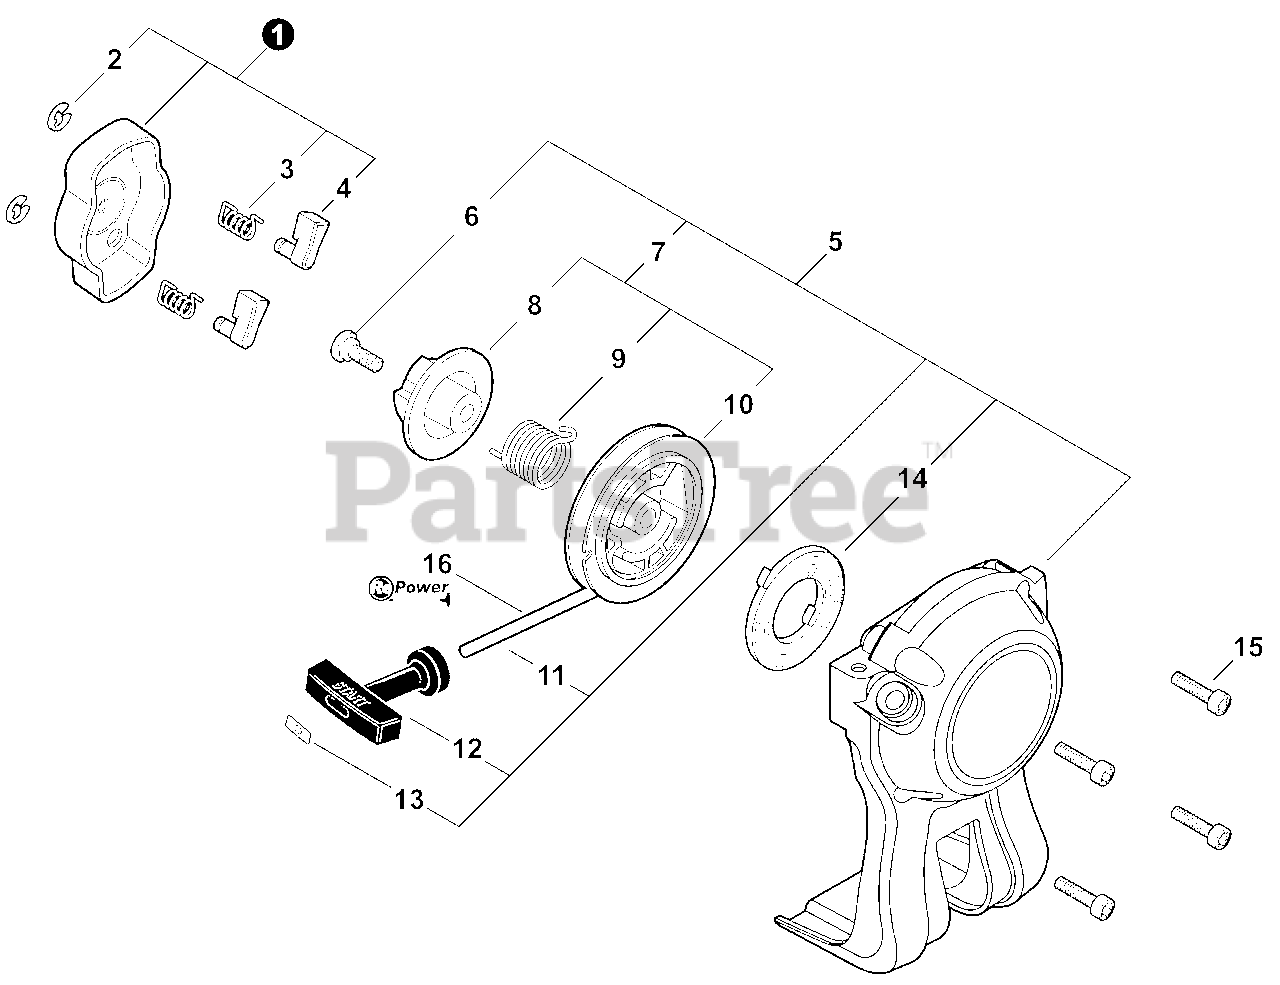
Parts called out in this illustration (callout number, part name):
1	PAWL ASSY, STARTER
2	E-RING 4
3	SPRING, RETURN
4	PAWL, STARTER
5	STARTER ASSY, RECOIL
6	SCREW
7	REEL/CAM PLATE SET
8	PLATE, CAM
9	SPRING, TORSION
10	REEL, ROPE
11	ROPE, STARTER
12	GRIP, STARTER
13	RETAINER, ROPE
14	SPRING, RECOIL
15	BOLT, TORX 4×16
16	ROPE, STARTER - REPOWER BULK Ø3
